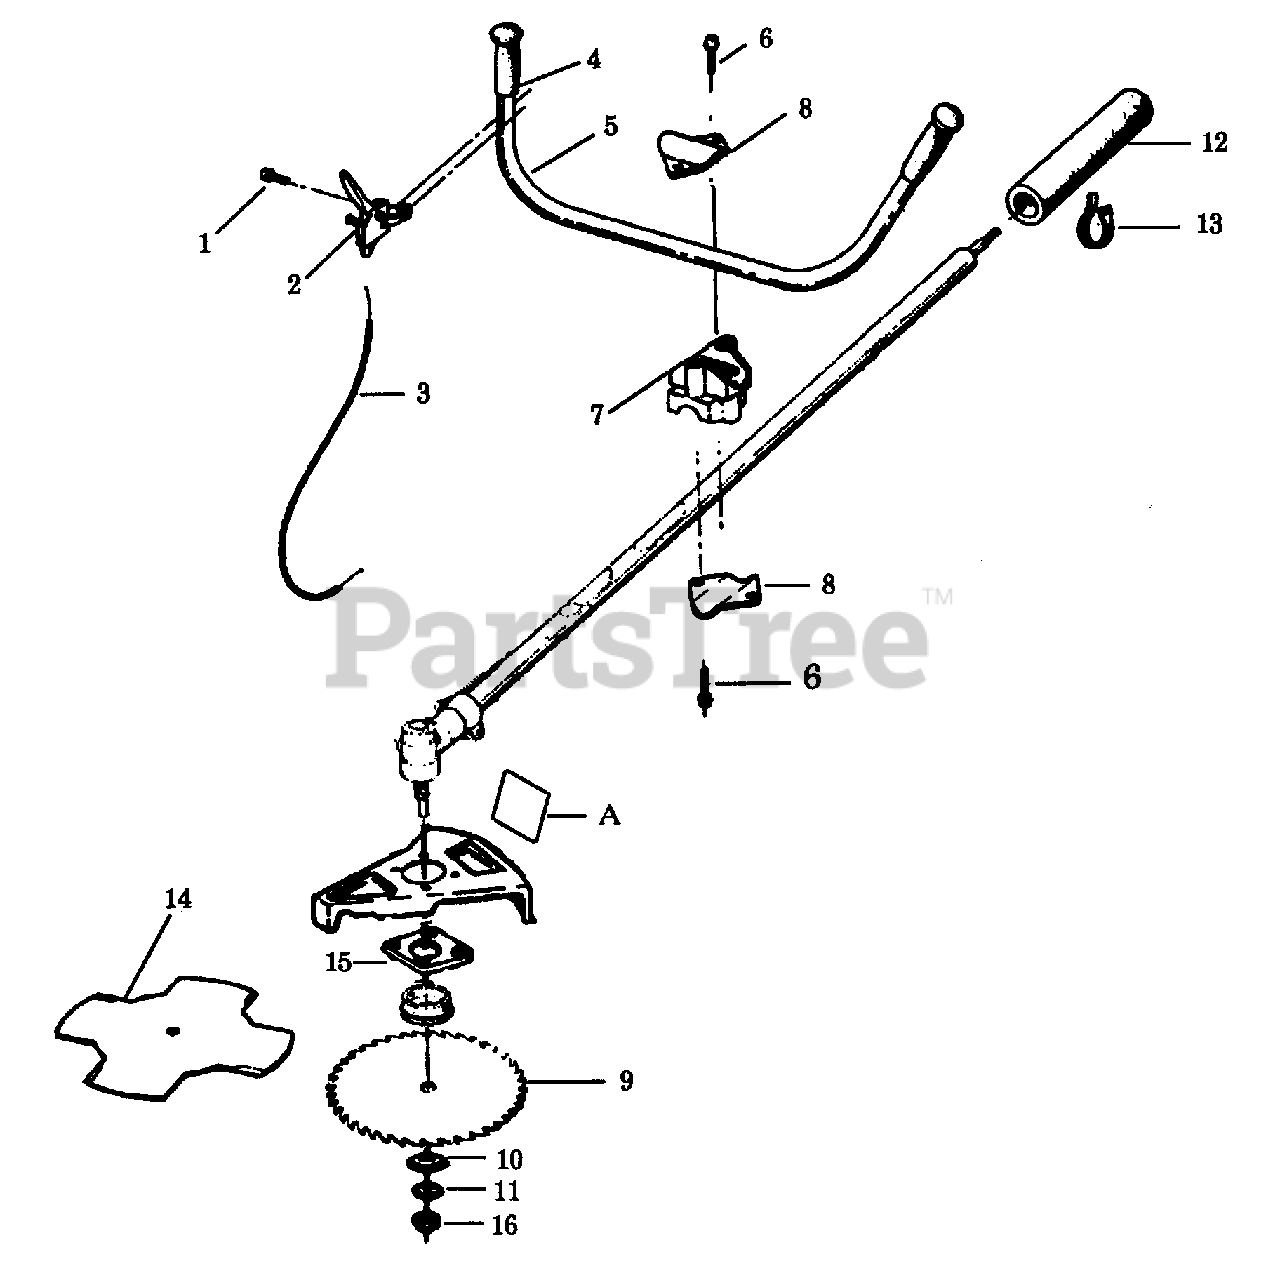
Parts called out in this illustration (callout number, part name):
2	Throttle Control Ass'y.
3	Throttle Cable
4	Handlebar Grip
5	Handlebar
7	Handlebar Clamp
8	Handlebar Bracket
9	Brush Blade-8"
11	Washer
12	Drive Shaft Pad
13	Tie Strap
14	Weed Blade-8"
15	Shield Retention Plate
A	Blade Rotation Decal (Not a serviceable part)
